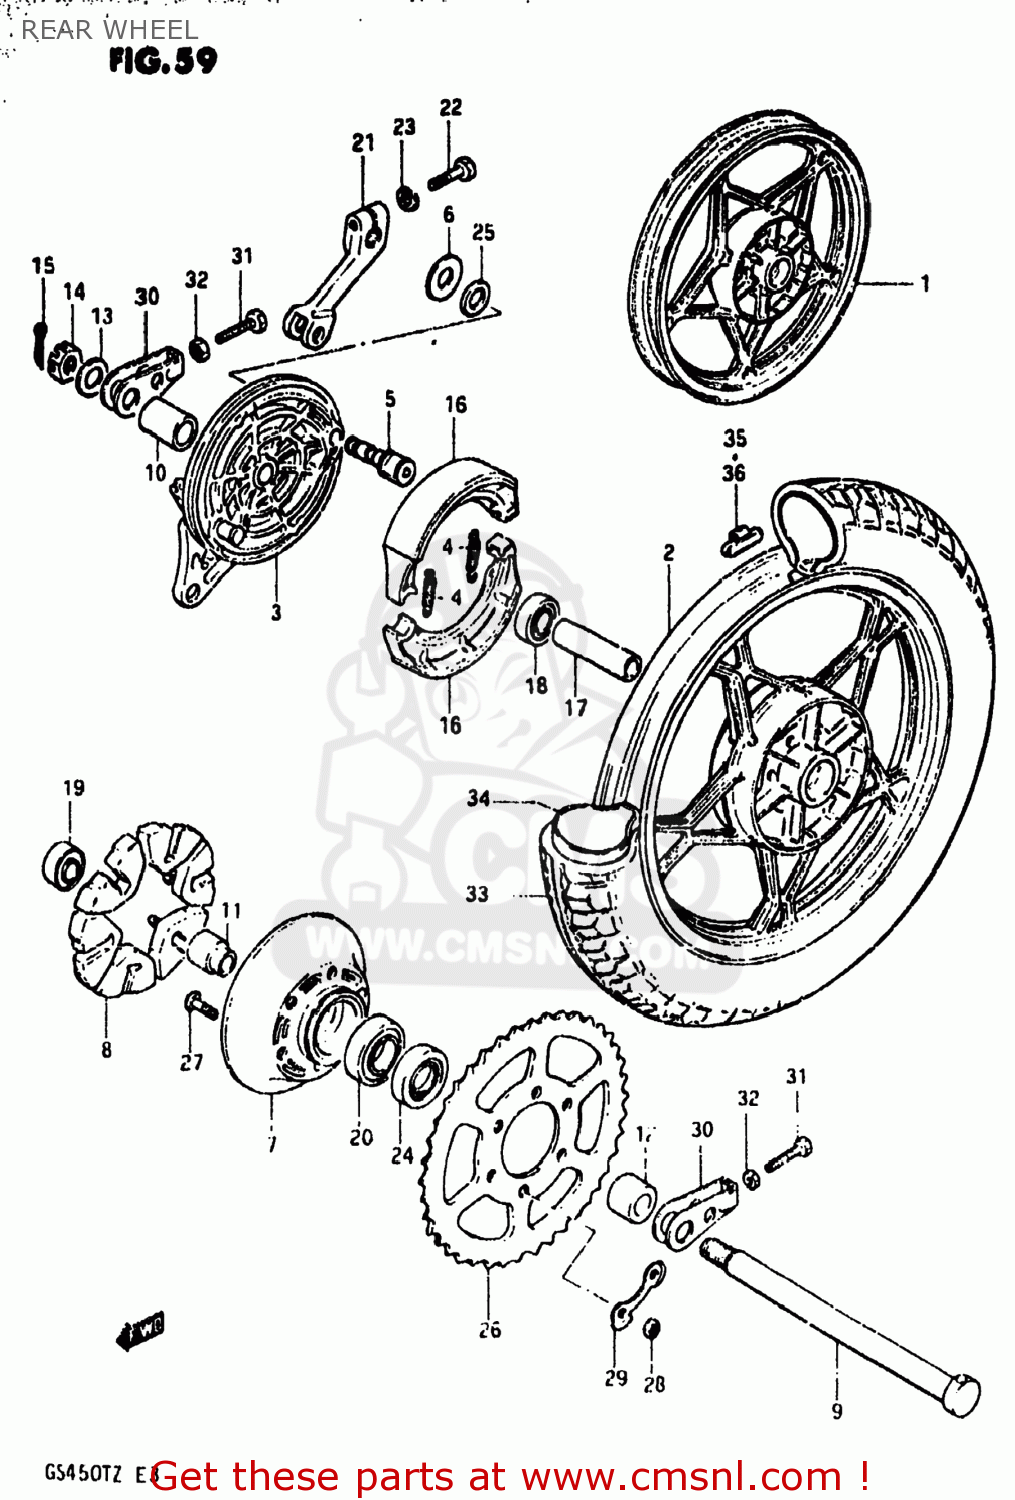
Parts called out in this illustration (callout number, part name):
1	WHEEL,REAR
2	WHEEL,REAR
3	PANEL,REAR HUB
4	SPRING,BRAKE SHOE
5	CAM,FRONT BRAKE
6	WASHER (15X24X1.6)
7	DRUM,REAR SPROCKET MOUNT
8	ABSORBER,RR HUB SHOCK
9	AXLE,REAR
10	SPACER(17.5X28X44.8)
11	SPACER,REAR HUB BEARING
12	SPACER(17X30.5X22.3)
13	WASHER (17X30X3.2)
14	NUT
15	PIN,COTTER
16	SHOE,BRAKE
17	SPACER (17.6X24X57)
18	BEARING
19	BEARING
20	BEARING
21	LEVER,RR BRAKE CAM
22	BOLT
23	LOCK WASHER
24	SEAL,OIL(30.5X52X8)
25	O-RING,BOSS
26	SPROCKET,REAR (NT:43)
27	BOLT
28	NUT
29	WASHER
30	ADJUSTER,CHAIN
31	BOLT
32	NUT
33	TIRE
34	TUBE ASSEMBLY,WHEEL,INNER
35	BALANCER,WHEEL
36	BALANCER,WHEEL
